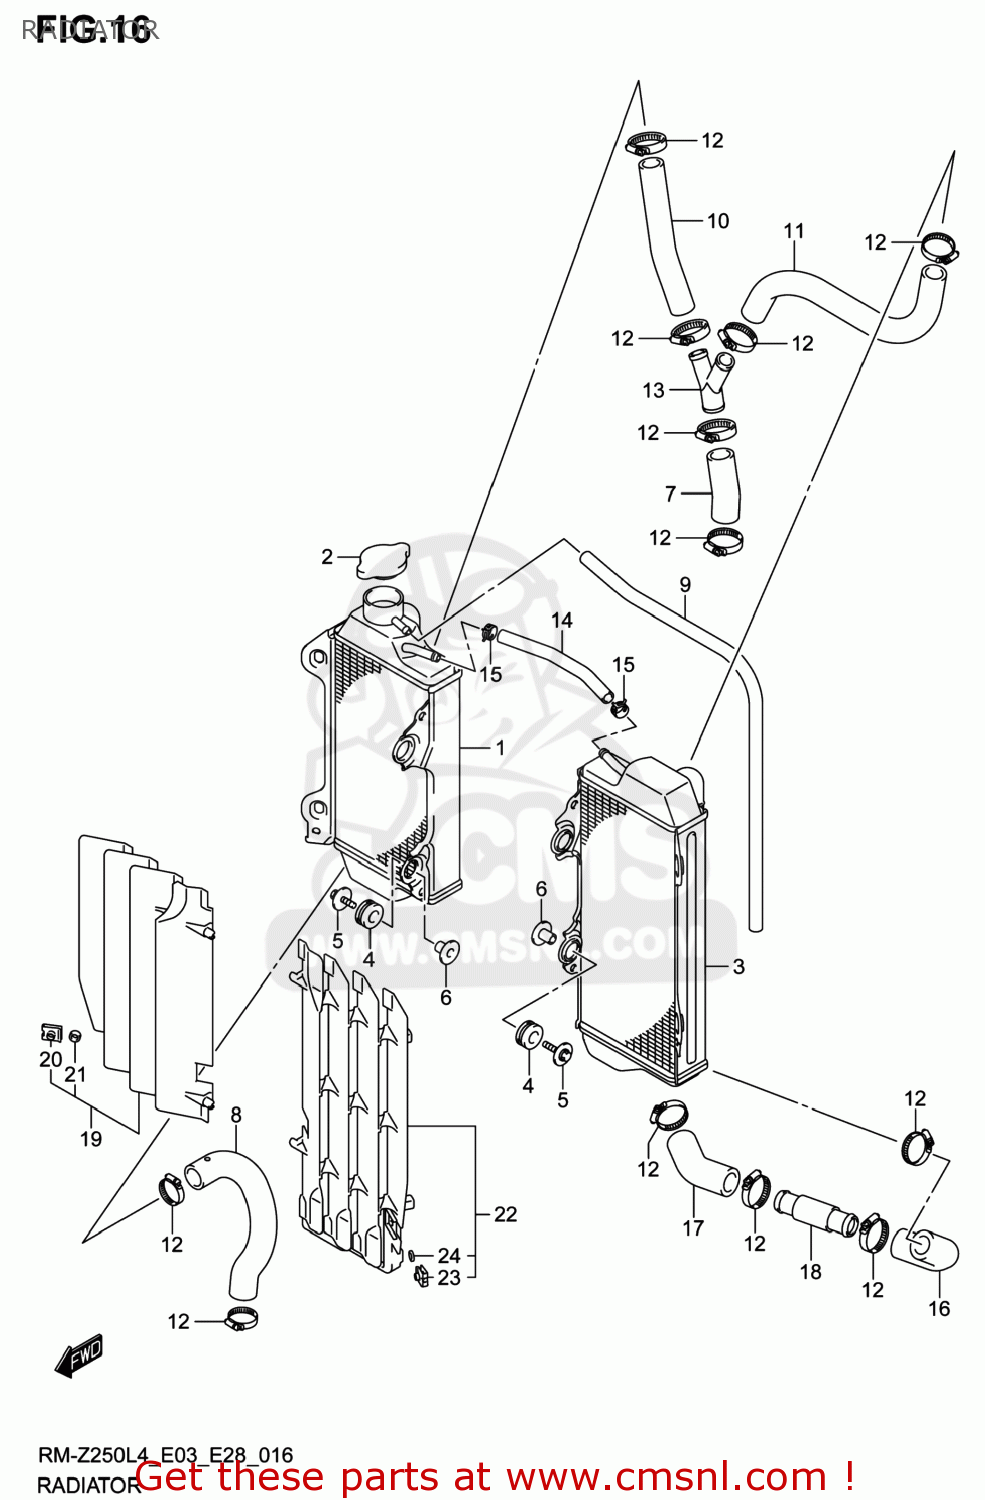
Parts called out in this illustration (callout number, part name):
1	RADIATOR,WATER,R
2	CAP,RADIATOR
3	RADIATOR,WATER,L
4	CUSHION,RADIATOR LWR
5	BOLT(6X25)
6	SPACER(6.5X10.5X14.1)
7	HOSE,RADIATOR INLET NO.1
8	HOSE,RADIATOR OUTLET NO.1
9	HOSE(5X8X1000)
10	HOSE,RADIATOR INLET NO.2
11	HOSE,RADIATOR INLET NO.3
12	CLAMP
13	JOINT,RADIATOR HOSE
14	HOSE,RADIATOR BYPASS
15	CLIP
16	HOSE,RADIATOR OUTLET NO.2
17	HOSE,RADIATOR OUTLET NO.3
18	PIPE,RADIATOR OUTLET
19	LOUVER,RADIATOR,R
20	NUT
21	SPACER(6.2X10X2.2)
22	LOUVER,RADIATOR,L
23	NUT
24	SPACER(6.2X10X2.2)
